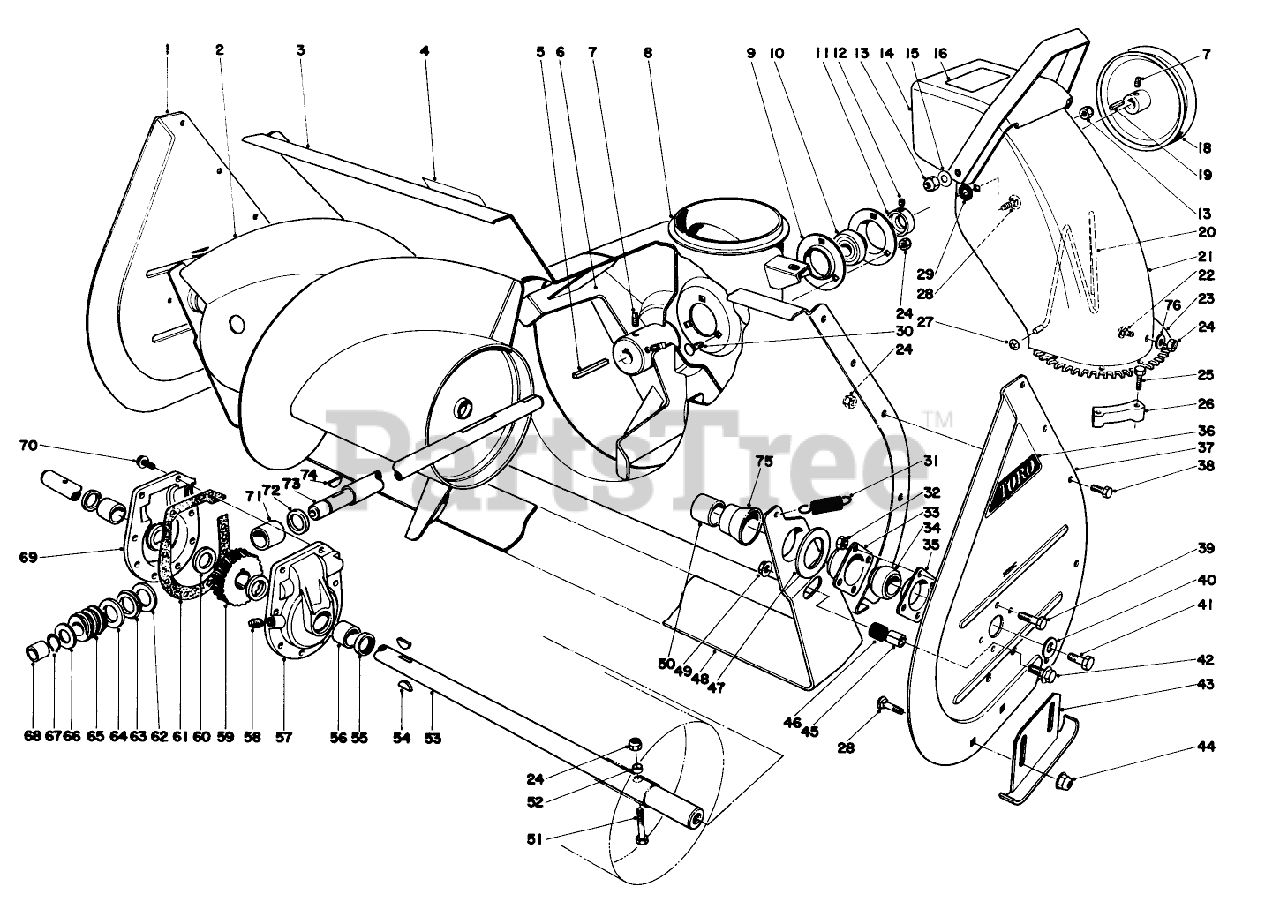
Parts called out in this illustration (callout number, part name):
3	AUGER HSG WA 32" *R
7	SCREW-SET, SQH
8	CHUTE RING
9	BRG FLANGE
10	BALL BRG W/COLLAR
11	EXT LOCKING COLLAR
12	SCREW-HSH
13	NUT-LOCK, CONE
15	WASHER-BELLEVILLE
19	SQUARE KEY
20	WIRE-CHUTE
22	SCREW-CARR
24	PART CAT OPC
25	SCREW-TAP
26	RETAINER-CHUTE
27	NUT-PUSH
28	SCREW-CARR
29	WASHER-RUBBER
30	BOLT-CARR
31	SPRING-TENSION
33	BEARING-FLANGE, FRONT
34	BEARING
35	BEARING-FLANGE, REAR
38	SCREW-HH
39	SCREW-HH
40	Flat Washer
41	SCREW-HH
42	SCREW-HHF
44	NUT-HHF, WHIZ
46	SCRAPER STOP CUSHION
47	SCRAPER BLADE SPACER
48	SCRAPER BLADE 32" *R
49	NUT-HF
52	SPACER-HUB, AUGER
54	KEY-WOODRUFF
55	SEAL-OIL
56	BUSHING
58	PLUG-PIPE, SQH
59	GEAR-WORM, 27T
60	WASHER-THRUST
62	WASHER-THRUST
63	BEARING-THRUST
64	THRUST-WASHER
66	WASHER-THRUST
67	RING-SNAP
68	BUSHING
70	SCREW-THD ROLL, HWH
71	BUSHING-SPECIAL
72	RING-QUAD
73	SHAFT-IMPELLER
74	KEY-WOODRUFF
76	WASHER-PLAIN
